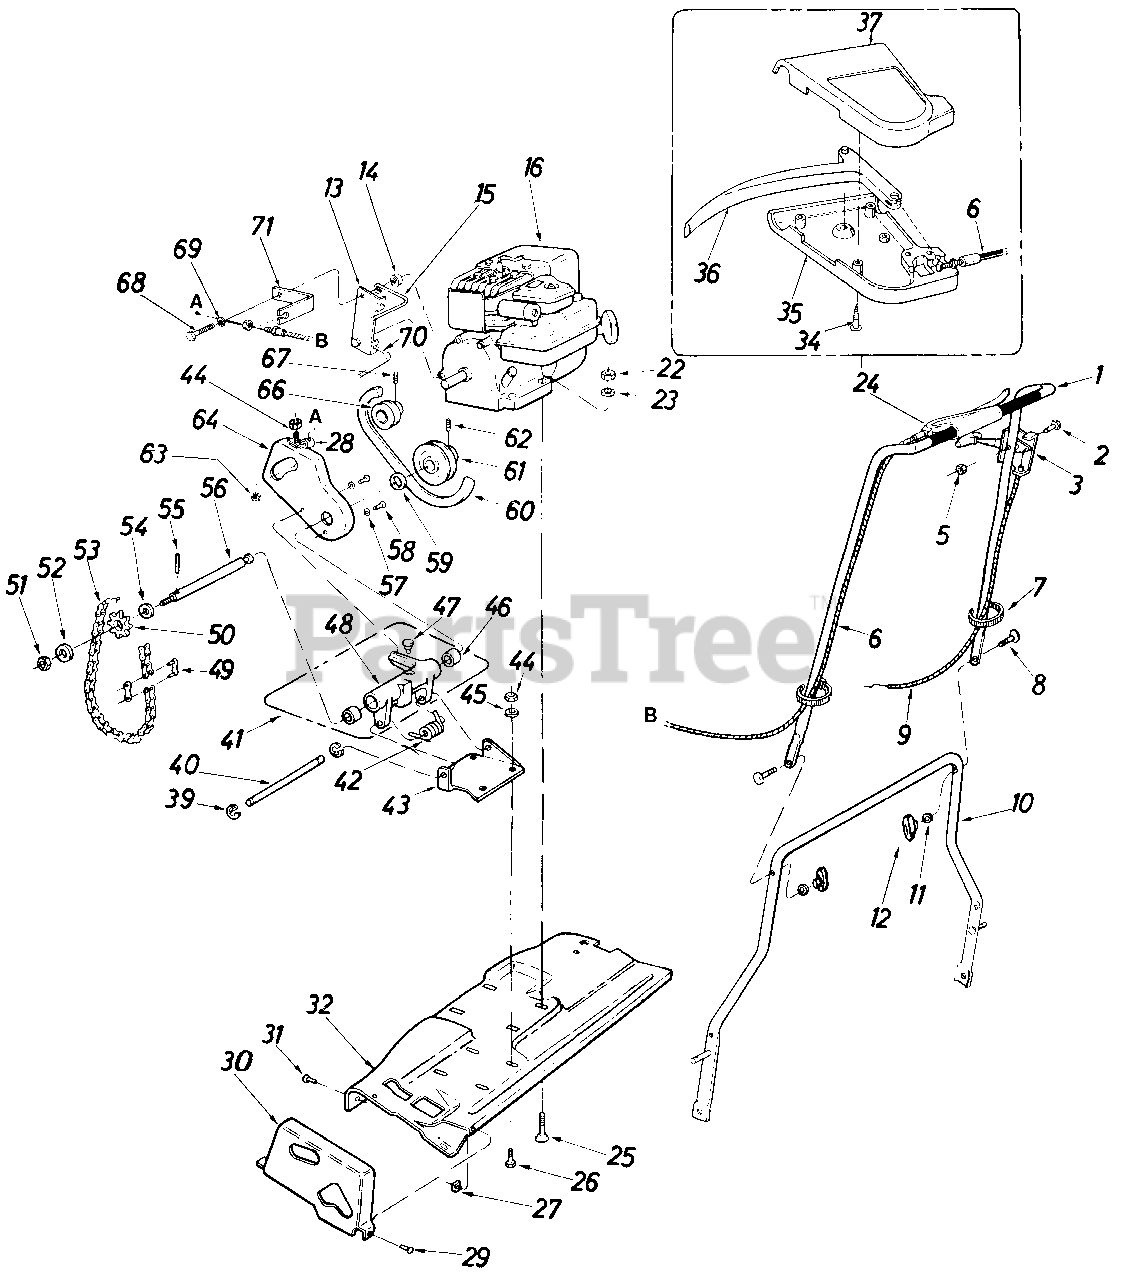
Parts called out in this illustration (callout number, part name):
1	Upper Hand le Ass'y.
2	Rd. Hd. Scr. 1/4-20 x 1.88" Lg.
3	Throttle Control Ass'y.
5	Capped Wash. Z-Nut
6	Clutch Control Cable
7	Cable Tie
8	Speclal Scr. 5/16-18 x 1.75" Lg.
9	Throttle Cable
10	Lower Handle Ass'y.
11	L-Wash. 5/16
12	Handle Knob
13	Belt Keeper Brkt.
14	Spacer
15	Belt Keeper-Upper
16	Engine
22	Hex Nut 5/16-18 Thd.
23	L-Wash. 5/16
24	Clutch Control Ass'y.
25	Carriage Bolt 5/16-18 x 1.375" Lg.*
26	Scr. 1/4-20 x .625 " Lg .
27	Hex L-Nut 10-32 Thd.
28	Clevis Lanyard Fitting
29	Ph. Hd. Scr. 10-32 x .375" Lg. *
30	Chain Guard
31	Hex Sems Scr. 5/16-24 x .50 Lg.*
34	Slotted Oval Self-Tap Scr. # 10 x .87 " Lg .
35	Rear Control Cover
36	Lever Clutch Control
37	Front Cover Control
39	Retaining Ring
41	Jack Shaft Hsg. and Brg. Ass'y.
42	Spri ng
43	Bracket
44	Hex Nut 1/4-20 Thd.
45	1/4 Split L-Wash.
46	Bearing
47	Oiler
48	Jack Shaft Hsg.
49	Connector Link
50	Sprocket
51	Hex Jam Nut 5/16-24
52	Washer
53	Chain
54	Wash. 5/8 x 15/16
56	Jack Shaft
57	Washer
58	Ph. Hd. Scr. 10-32 x .50" Lg.
59	Wash. 5/8 x 15/16
60	"V" Belt
61	Pulley Ass'y.
62	Roll Pin
63	Hex Nut 1/4-20 Thd.*
64	Belt Guard Ass'y.
66	Pulley
67	Set Scr. 5/16-24 x 7/32n Lg.
68	Ph. Hd. Scr. 1/4-20 x 1.75" Lg.
69	L-Wash. 1/4" Scr.*
70	Belt Keeper-Lower
71	Clutch Cable Bracket
